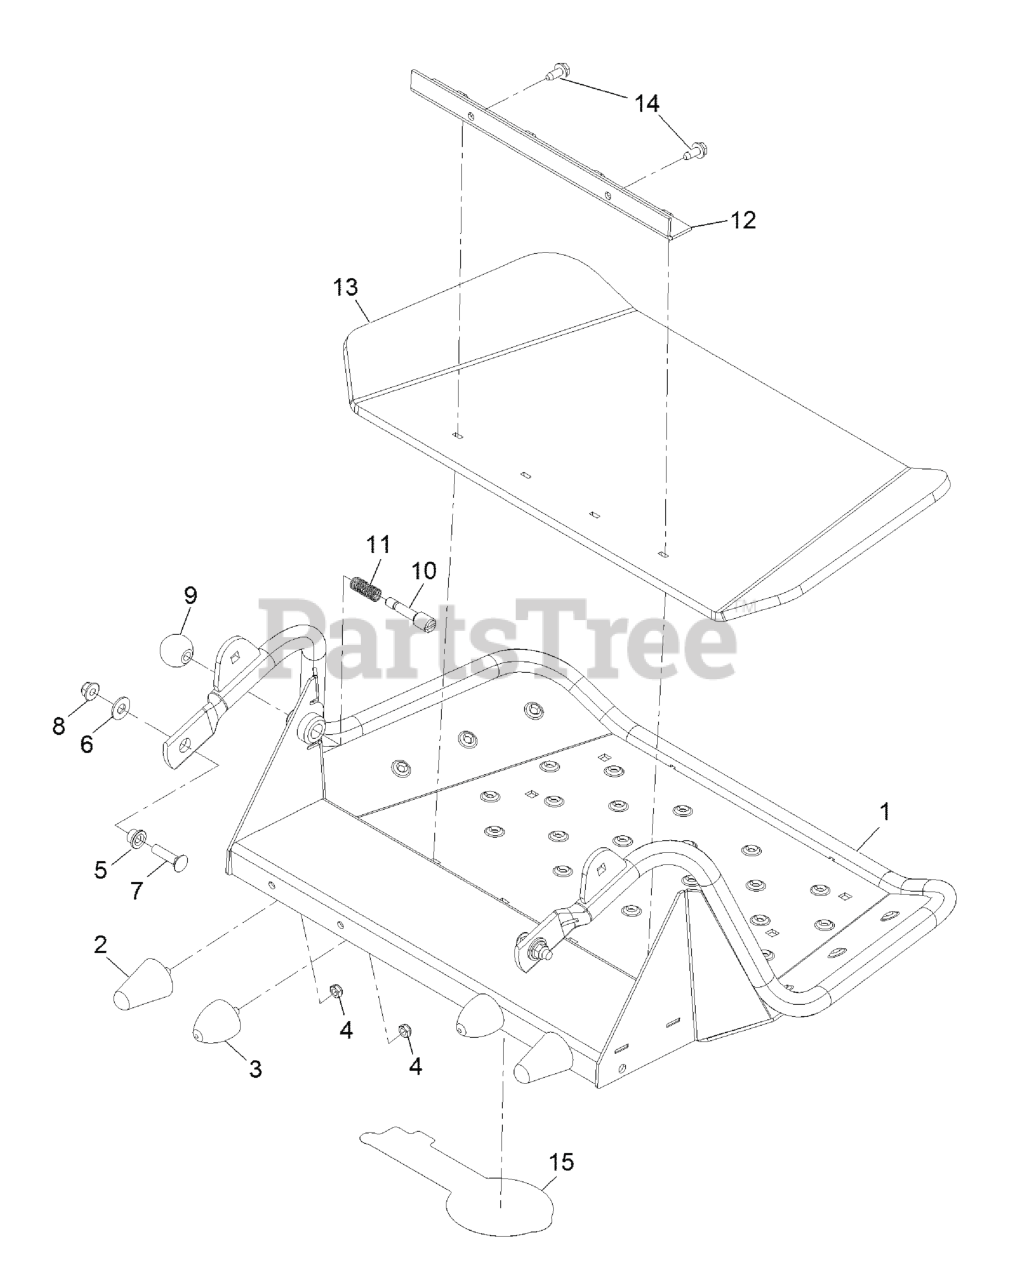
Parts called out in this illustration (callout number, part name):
1	PLATFORM ASM
2	BUMPER-RUBBER
3	BUMPER-RUBBER
4	NUT-LOCK, NI
5	BUSHING-FLANGED
6	WASHER-FLAT
7	SCREW-CARR
8	NUT-HF, NI
9	KNOB-BALL
10	PIN-LATCH
12	CLAMP-SHIELD
13	MAT-PLATFORM
14	Screw-HWH 5/16-18 X 3/4 Tf
15	DECAL-EXMARK LOGO
